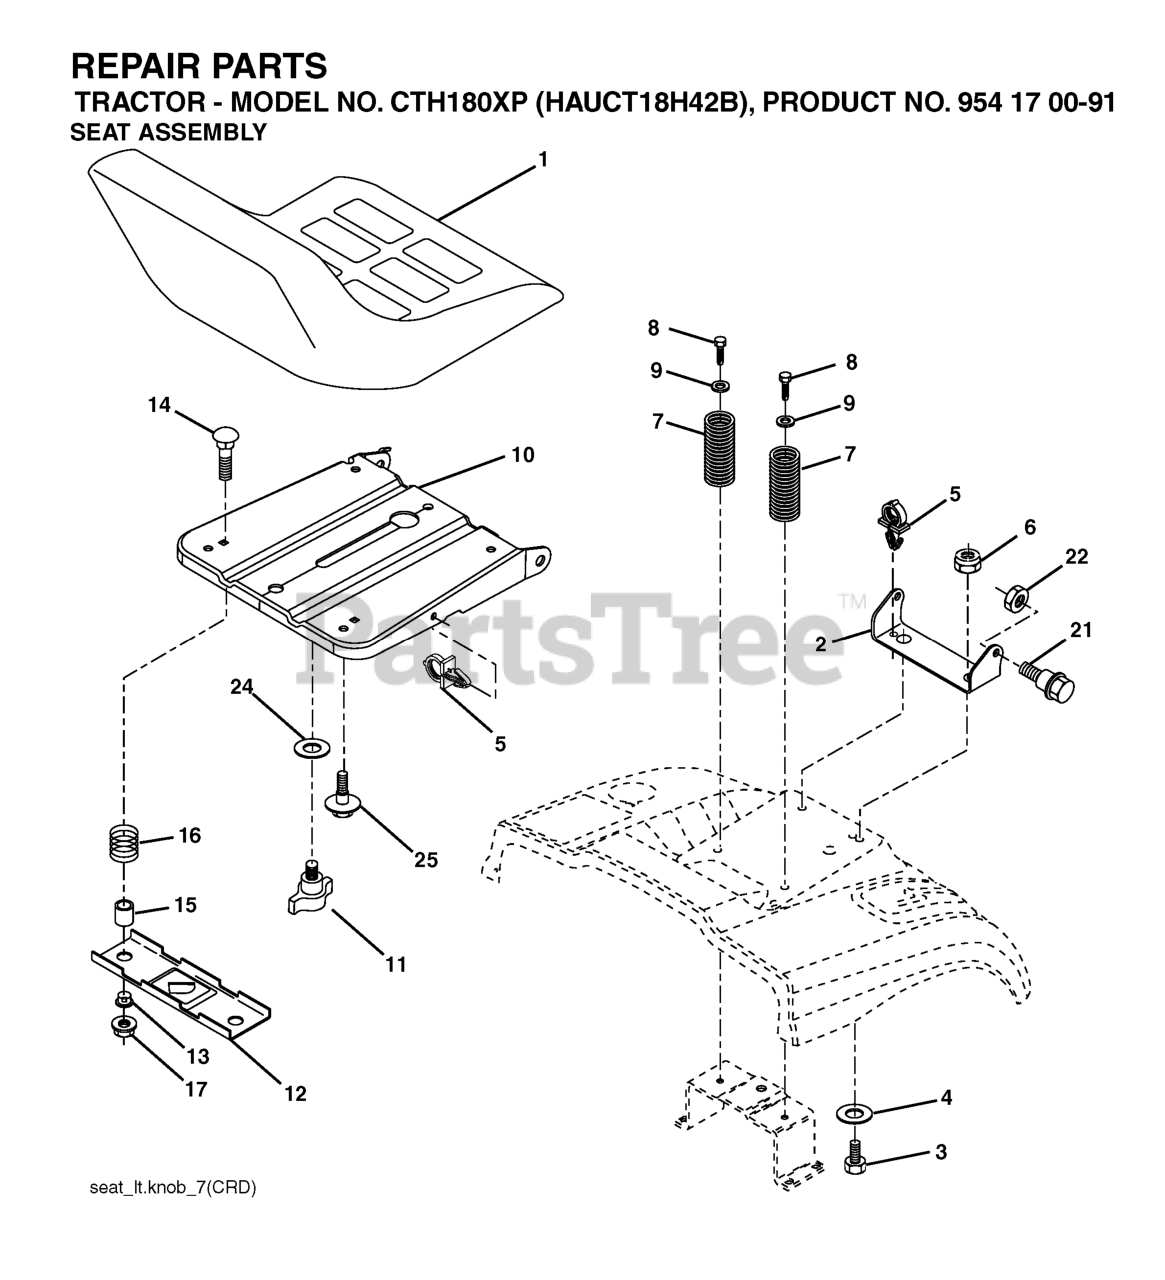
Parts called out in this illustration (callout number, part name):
1	SEAT, GRAY
2	SEAT PIVOT BRKT
3	BOLT, HEX 3/8-16X1
6	NUT
7	SPRING COMPRESSION
8	SCREW 3/8-16X1
9	WASHER
10	PAN SEAT
11	KNOB.SEAT.ADJ.WINGNUT
12	BRKT SWITCH
14	BOLT.ROUND.HEAD.SQUARE.NECK
15	SPACER SPLIT
16	SPRING COMPRESSED
17	NUT T
21	BOLT.SHOULDER.5/16-18
22	NUT.71038.31-18.HEX.NYLOCK
25	BOLT,SHOULD
